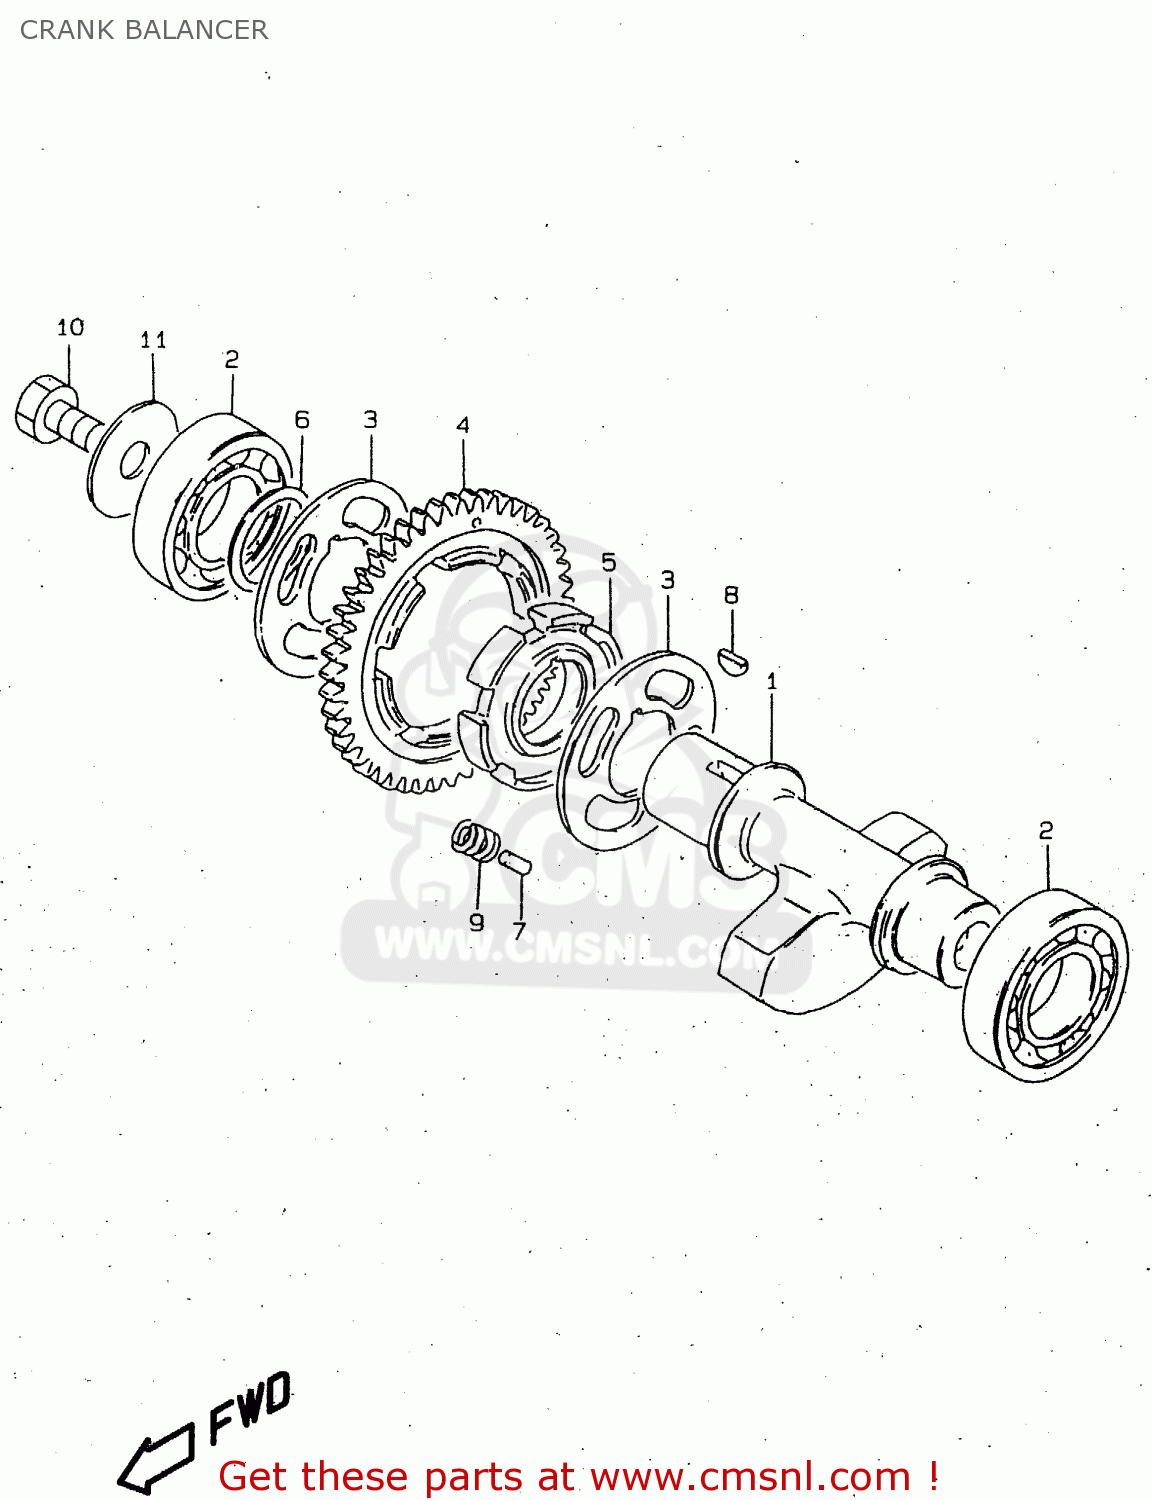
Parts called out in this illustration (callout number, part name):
1	SHAFT,CRANK BALANCER
2	BEARING(25X62X17)
3	WASHER
4	GEAR,CRANK BAL DRIVEN(NT:46)
5	RACE,CRK BAL DRIVEN GR INNER
6	SHIM
7	PIN(4.5X9.5)
8	KEY
9	SPRING
10	Bolt
11	WASHER(12X40X2.5)
